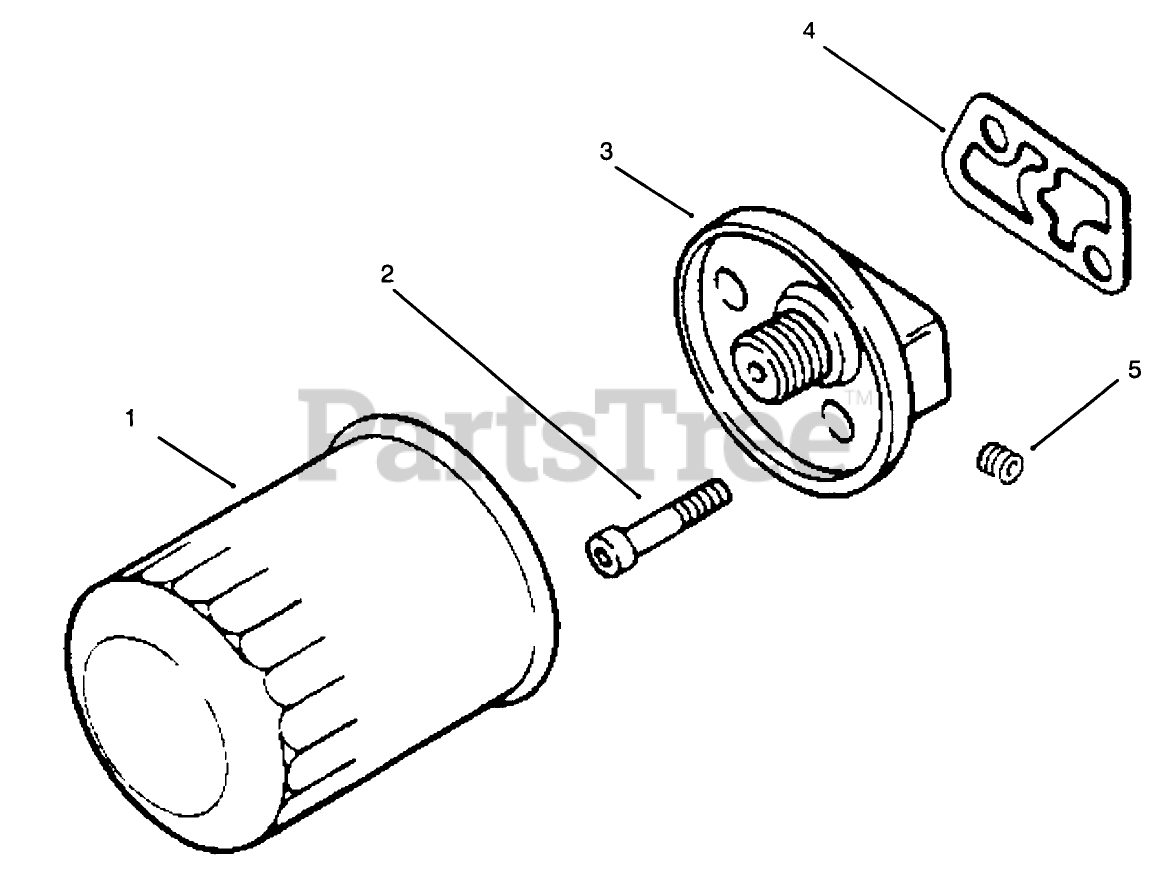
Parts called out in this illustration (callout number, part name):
1	Filter-Oil
2	Screw-H.C.
3	Adapter-Oil Filter
4	Gasket-Oil Filter
5	Plug
